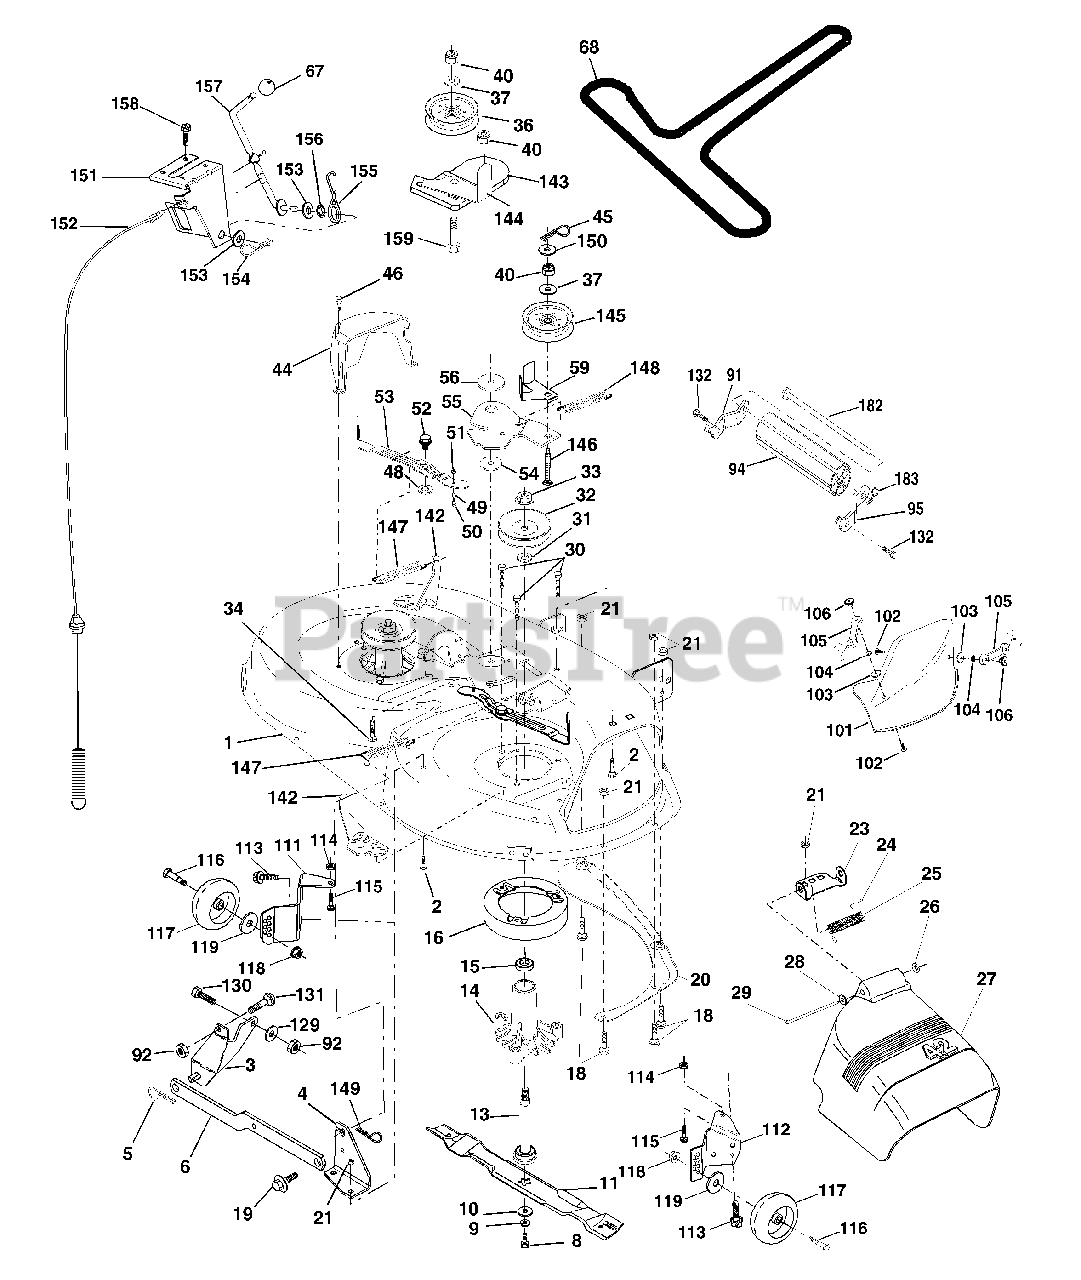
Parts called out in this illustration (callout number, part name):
1	Mower Deck Assembly, 42"
2	Bolt
3	Bracket Asm Fr. Sway Bar 3/42
4	Bracket Asm Deck 42" Sway Bar
5	Retainer Spring
6	Bar Sway Deck
8	Bolt 3/8-24 x 25 Grade 8 patched
9	Washer, Lock
10	Washer, Hardened
11	Blade, Mulching 42" Std
11	Blade Mower 42" Hi-Lift Std
13	Shaft Assembly, Mandrel, Vented
14	Housing, Mandrel, Vented
15	Bearing, Ball, Mandrel
16	Stripper, Mandrel Deck
18	Bolt, Carriage 5/16-18 x 5/8
19	Bolt, Shoulder
20	Baffle, Vortex
21	Nut
23	Bracket, Deflector Mower 42"
24	Cap, Sleeve 80 x 112 Blk Mower
25	Spring, Torsion, Deflector 2 52
26	Nut, Push Phos & Oil
27	Shield, Deflector 42" Blk
28	Washer 11/32 x 5/8 x 16 Gauge
29	Rod, Hinge 42" 6 75 W/G
30	Screw Thdrol
31	Washer, Spacer Mower Vented
32	Pulley, Mandrel
33	Nut, Toplock
34	Bolt
36	Pulley, Idler, Flat
37	Washer 13/32 x 13/16 x 16 Gauge
40	Nut
44	Guard, Mandrel, LH
45	Retainer
46	Screw, Thdrol 1/4-20 x 5/8 T
48	Washer, Hardened
49	Roller Assembly, Cam Follower
50	Bolt, Shoulder #10-24 Grade 5
51	Locknut
52	Bolt, Shoulder 5/16-18 UNC
53	Arm Assembly, Pad, Brake
54	Washer, Hardened
55	Arm, Idler
56	Spacer, Retainer
59	Guard TUV Idler
67	Knob Round
68	V-Belt, 42" Mower
91	Bracket Asm Noseroller LH
94	Roller Nose 38 & 42
95	Bracket Asm Noseroller RH
101	Mulcher Cover
102	Screw, Pan Hd Phillip 10-24 x 5/8
103	Washer, Flat
104	Washer, Lock
105	Latch Assembly
106	Nut, Weld
111	Bracket, Gauge, Wheel LH
112	Bracket, Gauge, Wheel RH
113	Screw 3/8-16 x .625
114	Bolt Carr. 5/16-18 x 5/8
115	Nut Keps 5/16-18 UNC
116	Bolt, Shoulder
117	Wheel, Gauge
118	Nut Centerlock 3/8-16
119	Washer 3/8 x 7/8 x 14 Ga.
132	Screw 3/8-16 x .75
142	Arm Spring Brake Mower
143	Bracket Arm Idler 42"
144	Keeper Belt 42" Clutch Cable
145	Pulley Idler Flat
146	Bolt Carriage Idler
147	Spring Extension
148	Spring Return Idler
149	Retainer Spring Yellow
150	Washer 9/32 x 3/4 x 16 Ga.
151	Bracket Clutch Cable
152	Clutch Cable 42"
153	Washer Flat 3/8" Type B
154	Spring Retainer
155	Spring Retention LVR CLTCH CAB
156	Spacer Clutch Cable
157	Rod Clutch Cable 3/8"
158	Screw Hex Thd Cut 1/4-20 x 5/8
159	Bolt Rdhd Sqn 3/8-16 UNC x 1-3/4
182	Rod Roller Nose
183	Retainer Spring
